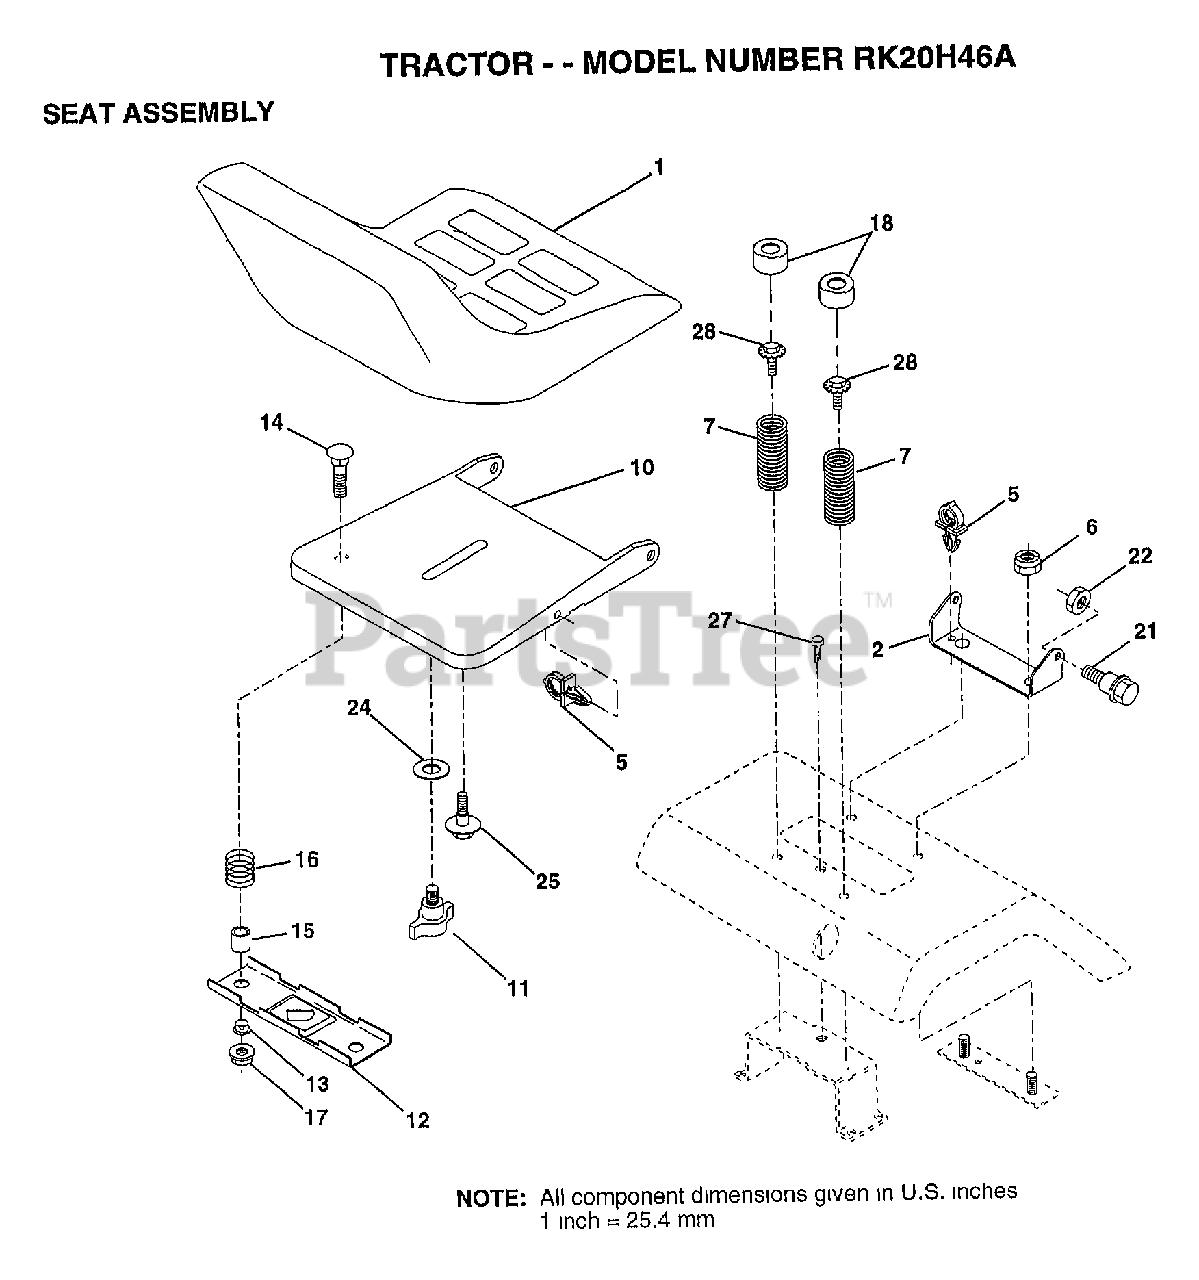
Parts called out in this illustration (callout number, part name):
1	SEAT.2500/1516.BK
2	BRACKET PVT SEAT
3	NUT
5	CLIP.PUSH-IN.HING
7	SPRING COMPRESSIO
10	PAN-SEAT
11	KNOB.SEAT.ADJ.WINGNUT
12	BRKT SWITCH
13	BUSHING
14	BOLT-RD HD SQ NK
15	SPACER SPLIT
16	SPRING COMPRESSED
18	CAP SPRING
21	"BOLT,SHOULDER"
22	NUT
24	WASHER
25	"BOLT,SHOULDER"
27	SCREW LT
28	BOLT.5/16-18.UNC
